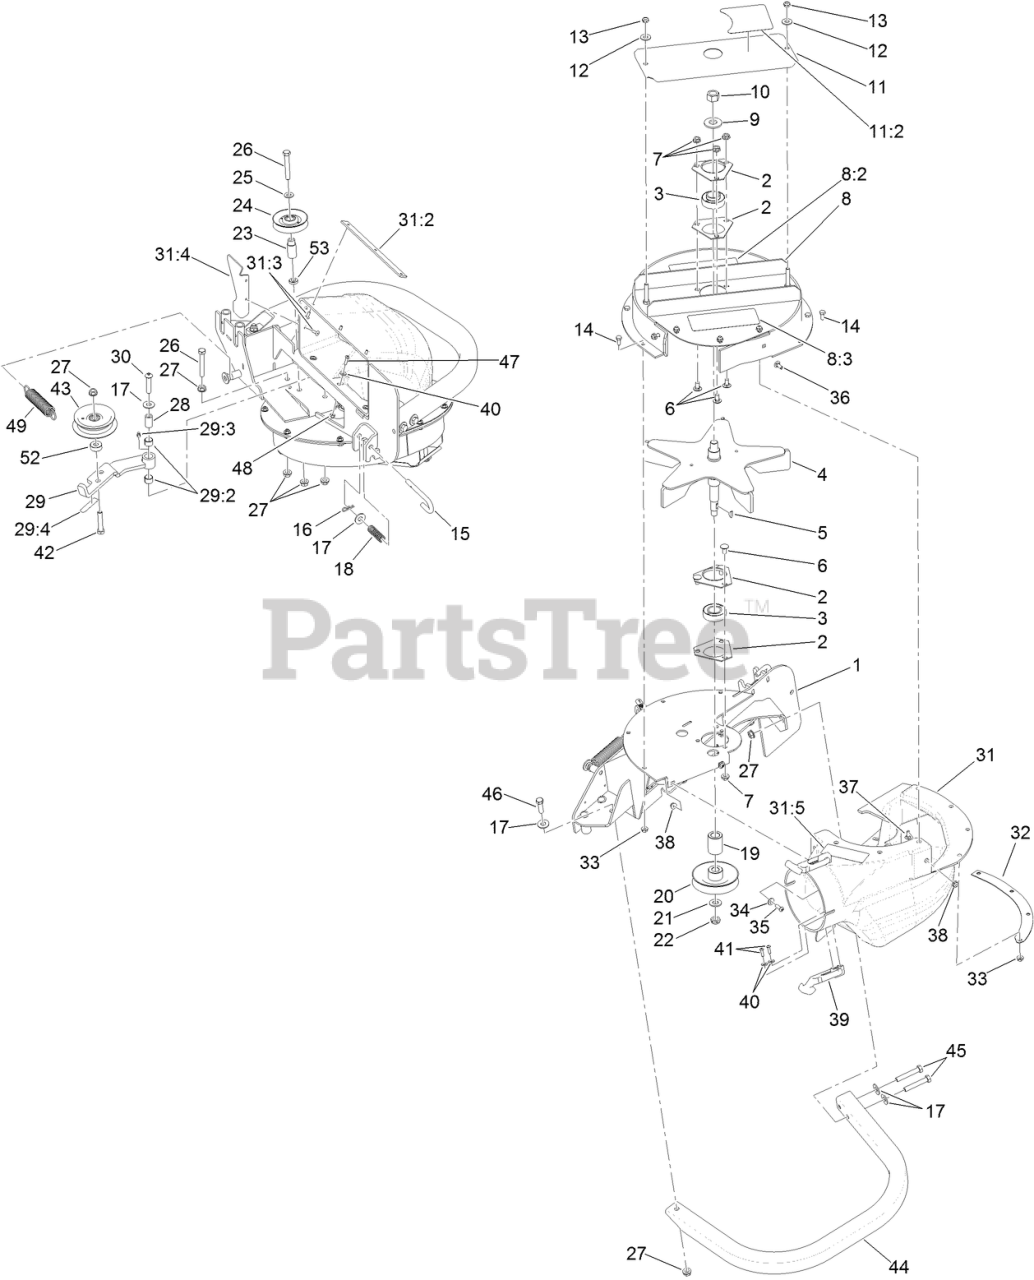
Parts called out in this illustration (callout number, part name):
1	MOUNT-BLOWER
2	HOUSING-FLANGE
3	BEARING
4	IMPELLER
5	KEY-WOODRUFF
6	SCREW-CARR
7	NUT-HF
8	UPPER-HOUSING W/DECALS
8:2	DECAL-WARNING
8:3	DECAL - E-Z VAC
9	WASHER-SPRING
10	NUT-HEX
11	COVER-BEARING W/DECAL
11:2	DECAL-WARNING
12	WASHER-FLAT
13	NUT-LOCK, NI
14	SCREW-HH
15	PIN-LATCH
17	WASHER-FLAT
18	SPRING-COMPRESSION
19	SPACER
20	PULLEY
21	WASHER-FLAT
22	NUT-LOCK, NI
24	IDLER-INSIDE
25	WASHER-FLAT
26	SCREW-HH
27	NUT-HHF, WHIZ
28	BUSHING-PIVOT, IDLER
29	IDLER ARM ASM W/BUSHINGS
29:2	BUSHING
29:3	FITTING-GREASE
29:4	DECAL-WARNING
30	SCREW-HSBH
31	BLOWER CHUTE ASM
31:2	PLATE-REINFORCEMENT
31:3	RIVET-BLIND
31:4	PLATE-FILLER
31:5	DECAL-WARNING
32	PLATE-BACKING, BLOWER
33	NUT-HF
34	WASHER-FLAT
35	SCREW-HSBH
36	BOLT-CARR
37	SCREW-CARR
38	NUT-HF
39	LATCH-RUBBER
40	WASHER-FLAT
41	SCREW-HSBH
42	SCREW-HH
43	IDLER-FLAT
45	SCREW-HH
46	SCREW-HH
47	SCREW-HSBH
48	NUT-LOCK, NI
49	SPRING-EXTENSION
52	SPACER
53	SPACER
